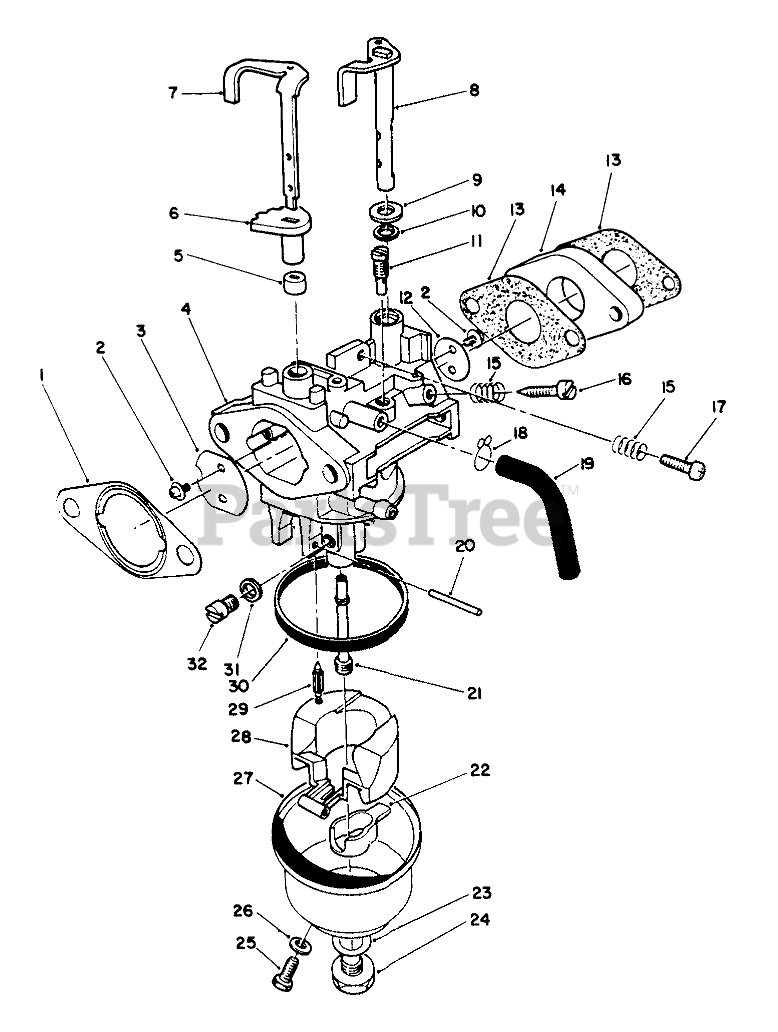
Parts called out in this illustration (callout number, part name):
1	GASKET F/W ENGINE
2	Screw
3	VALVE
4	Body-Carburetor
5	LOWER CHOKE RING
6	UPPER CHOKE RING
7	SHAFT
8	SHAFT
9	WASHER
10	Seal-Throttle Shaft
11	JET - PILOT
12	VALVE
13	GASKET INTAKE
14	INSULATOR - CARB.
15	SPRING-PILOT SCREW
16	ADJUSTER
17	SCREW
18	CLAMP
20	Pin
21	NOZZLE - MAIN
22	SPACER
23	GASKET
24	SCREW
25	SCREW
26	GASKET
28	FLOAT
29	NEEDLE
30	FLOAT BOWL GASKET
31	SPACER
32	JET - MAIN
